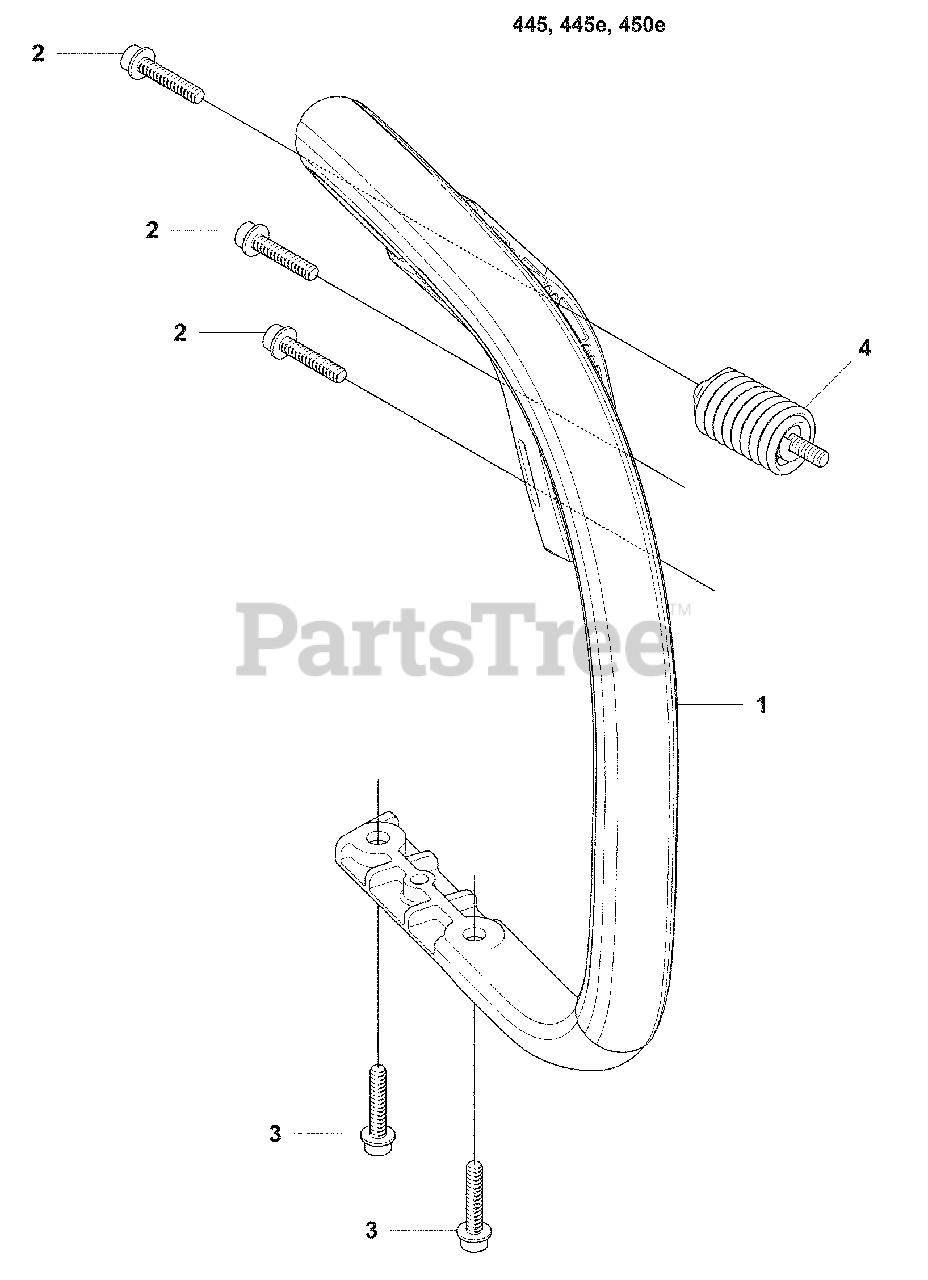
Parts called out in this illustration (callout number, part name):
1	Front Handle
2	Screw, 3 X 25 IHSCFT
3	Screw, STC 6Sf St6.3
4	Insulator
